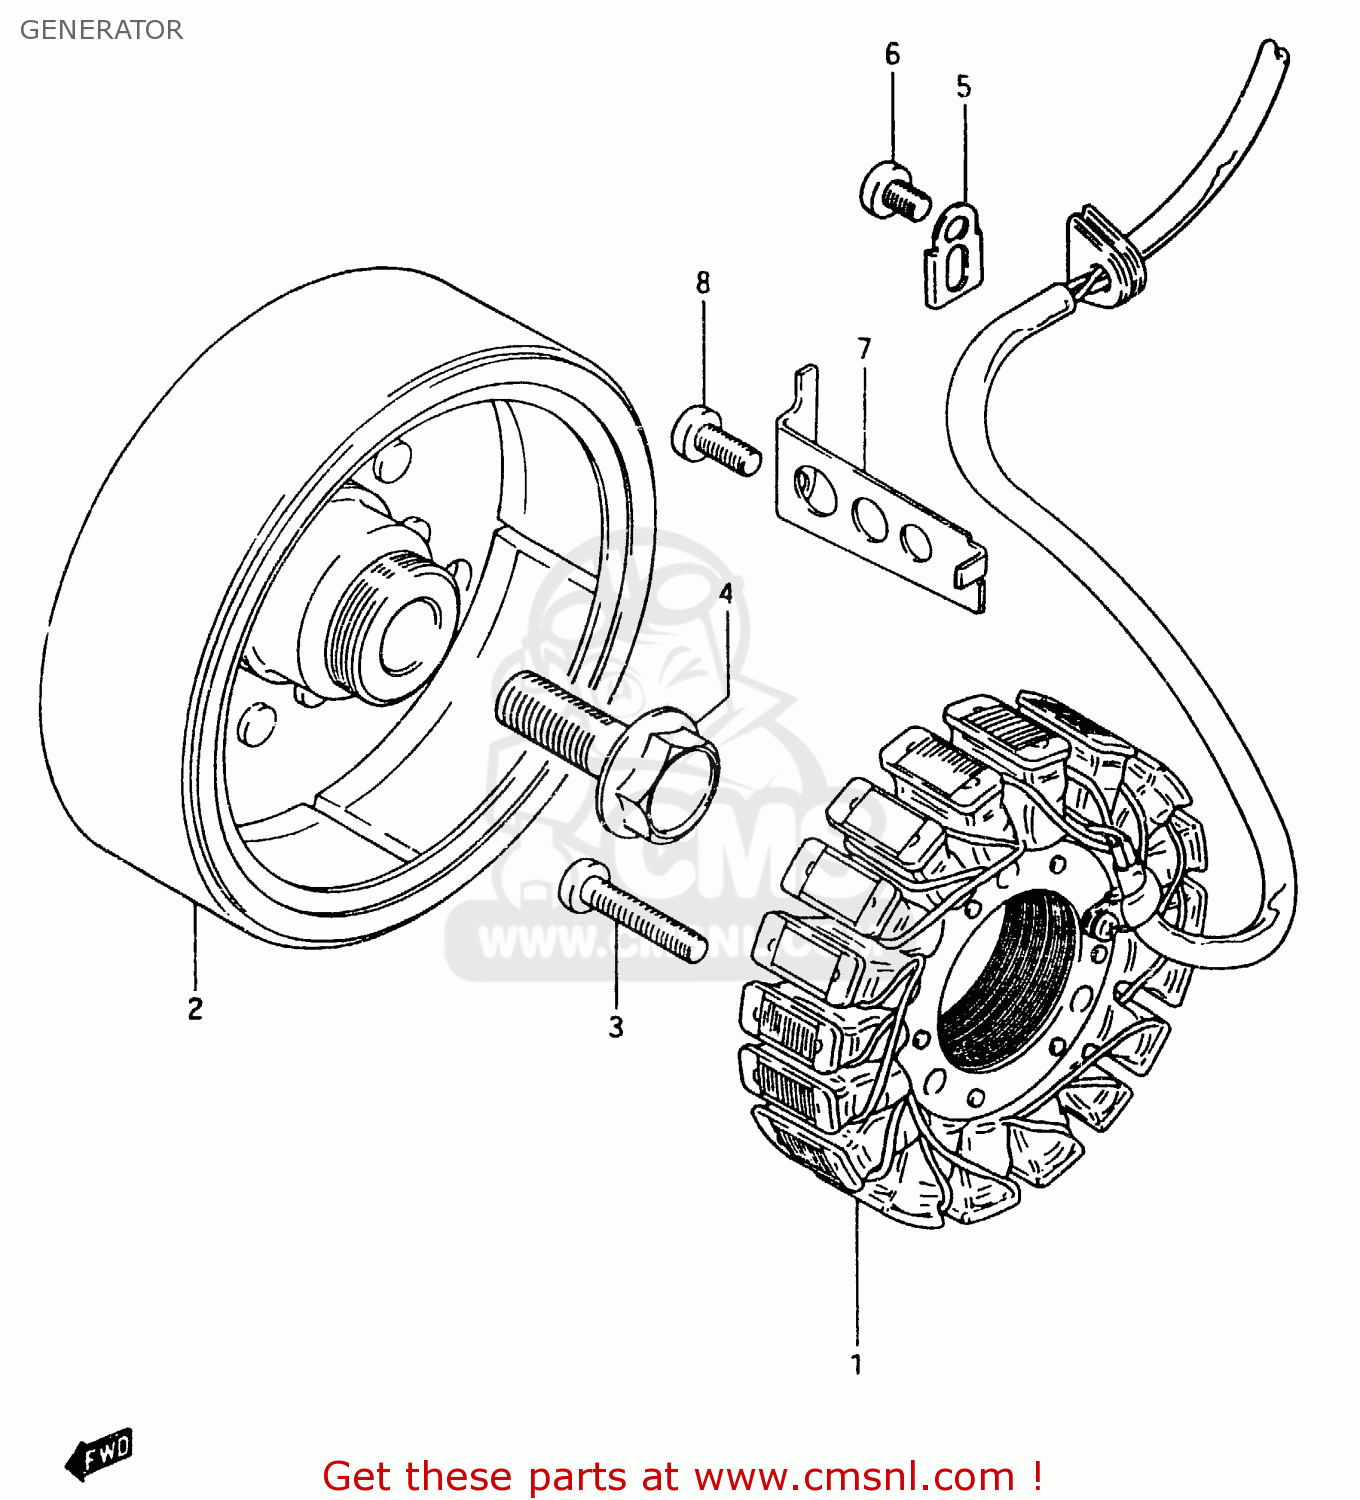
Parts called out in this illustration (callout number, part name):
1	STARTER ASSY
2	ROTOR ASSY
3	SCREW 6X30
4	BOLT(14X43)
5	CLAMP,GENERATOR LEAD WIRE
6	SCREW
7	CLAMP,GENERATOR LEAD WIRE
8	SCREW
